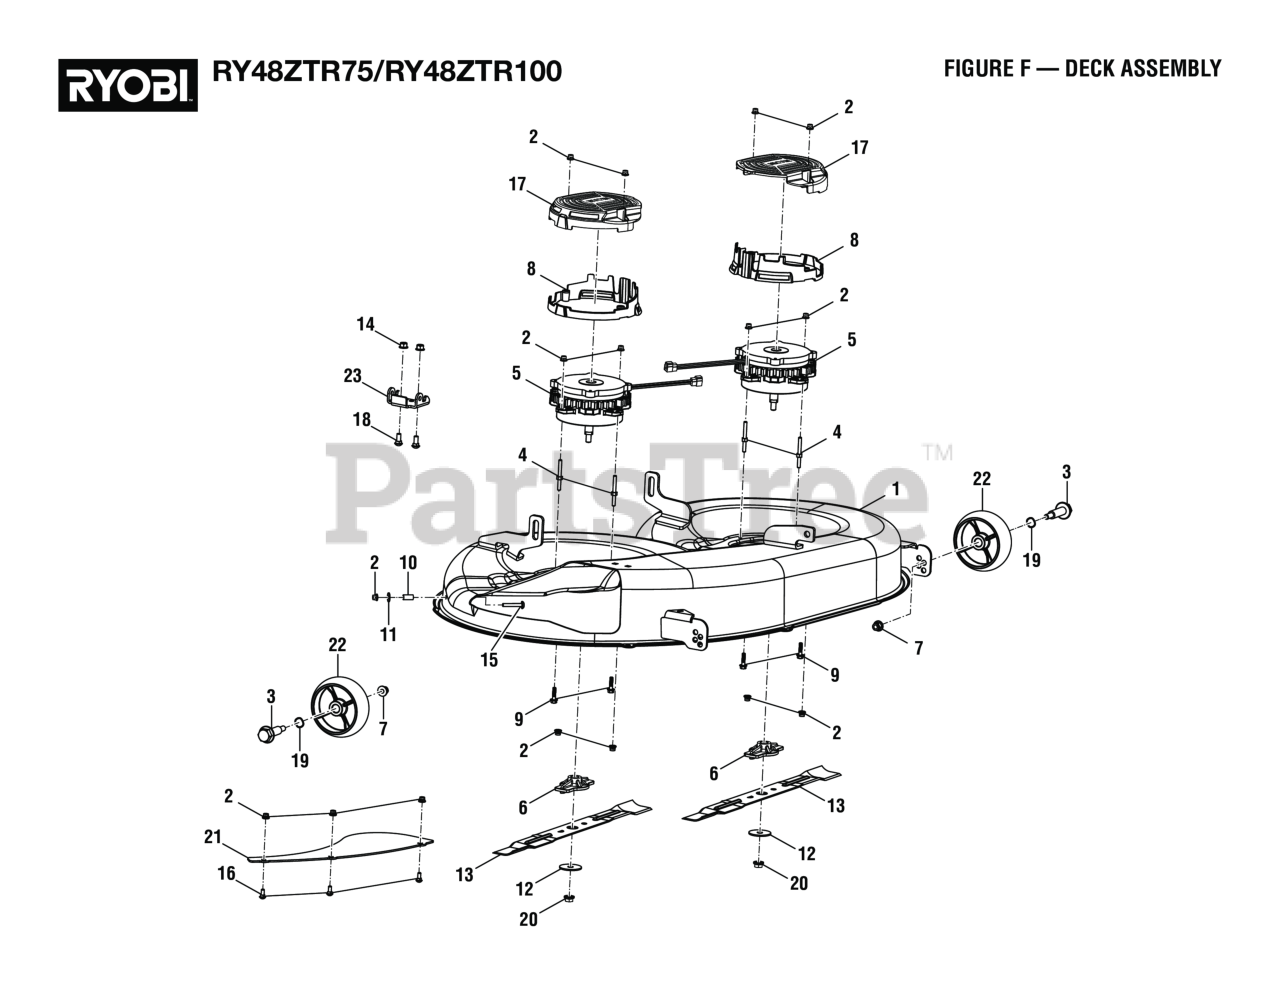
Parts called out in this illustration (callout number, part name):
1	Deck, 42 in
2	Flange Lock Nut (M6 x 1.00)
3	Shoulder Bolt (M10 x 70 mm)
4	Threaded Stud (M6 x 35 mm)
5	Deck Motor
6	Blade Adapter
7	Lock Nut (M10 x 1.5 mm)
8	Deck Motor Cover, Bottom
9	Flange Bolt (M6 x 25 mm, Hex Hd.)
10	Deck Bagger Chute Mounting Shaft
11	Washer (OD18 x ID6.4 x 1.6t)
12	Blade Retainer Washer
13	21 in. Blade
14	Flange Nut (M8) (For Drive Motor Controller V)
15	Screw (M6 x 40, Soc Hd.)
16	Carriage Bolt (M6 x 16 mm)
17	Deck Motor Cover, Top
18	Carriage Bolt (M8 x 20 mm)
19	Spring Washer (OD20.5 x ID17 x 0.3t)
20	Flange Lock Nut (M10 x 1.25)
21	Deck Baffle (42 in.)
22	Front Deck Roller Wheel (124.5 Dia.)
23	Discharge Chute Mounting Bracket
